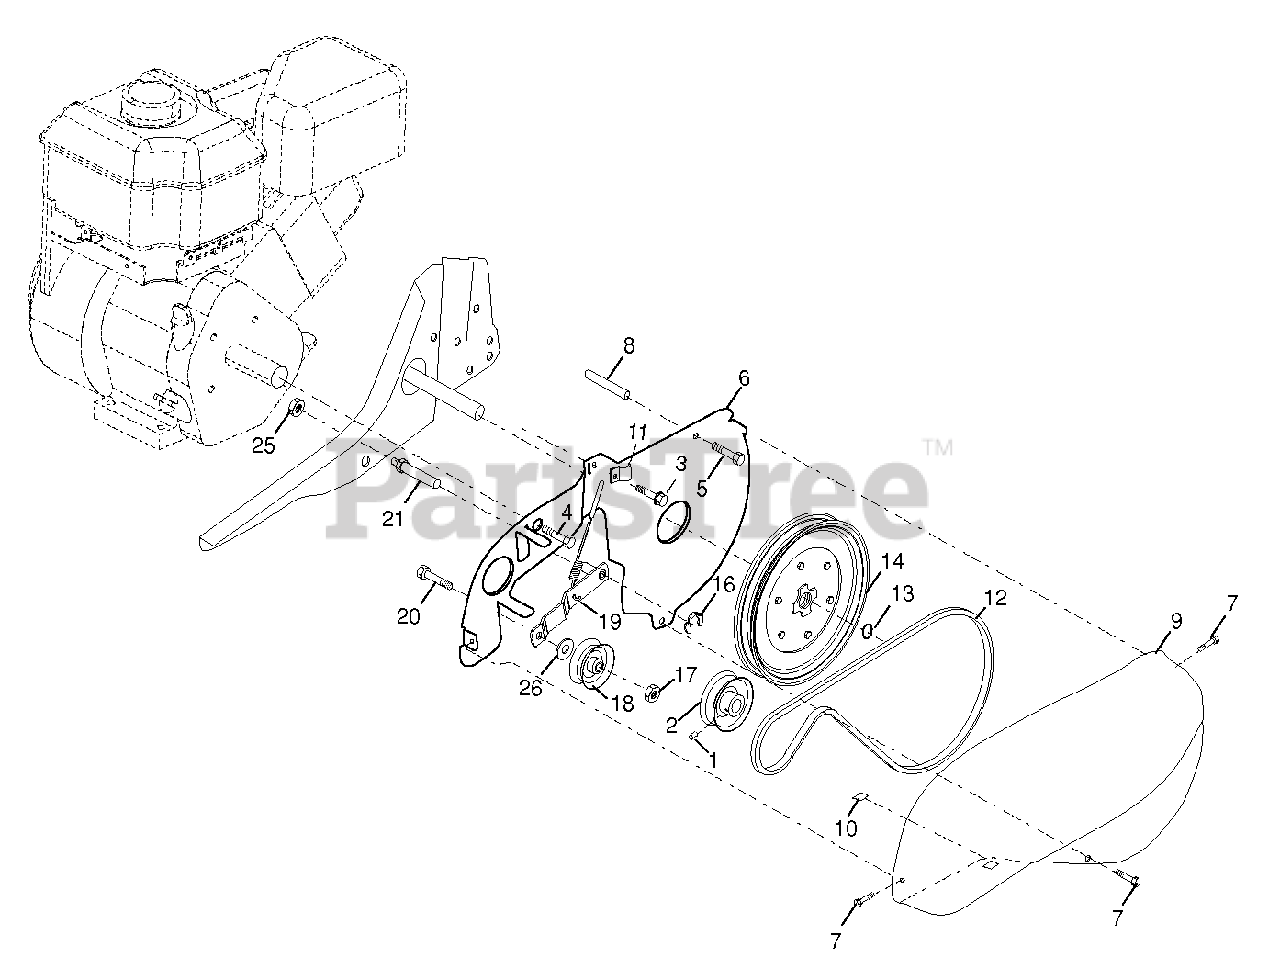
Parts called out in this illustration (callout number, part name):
1	SET SCREW
2	ENGINE PULLEY
3	SCREW.HXTAP.10-24
5	BOLT, THD ROLLER 1/4-20 X 2-1/
6	SHIELD.INNER.FRT.BLACK
7	SCREW.HEX.WSH.SLT.#10-24X.50
8	SPACER.SPLIT
9	GUARD, BELT
10	PAD IDLER TI
11	CLIP.PLATED
12	V BELT STD
13	RETAINING RING LT
14	SHEAVE.TRANS
16	KLIP RING TI
17	NUT.LOCK.5/16-18
18	PULLEY.W/SPACER.2.25
19	ARM.ASM.IDLER.PNT
20	HEX BOLT
21	SHAFT.IDLER.TILLER
25	JAM NUT TI
26	WASHER.20X8.5
